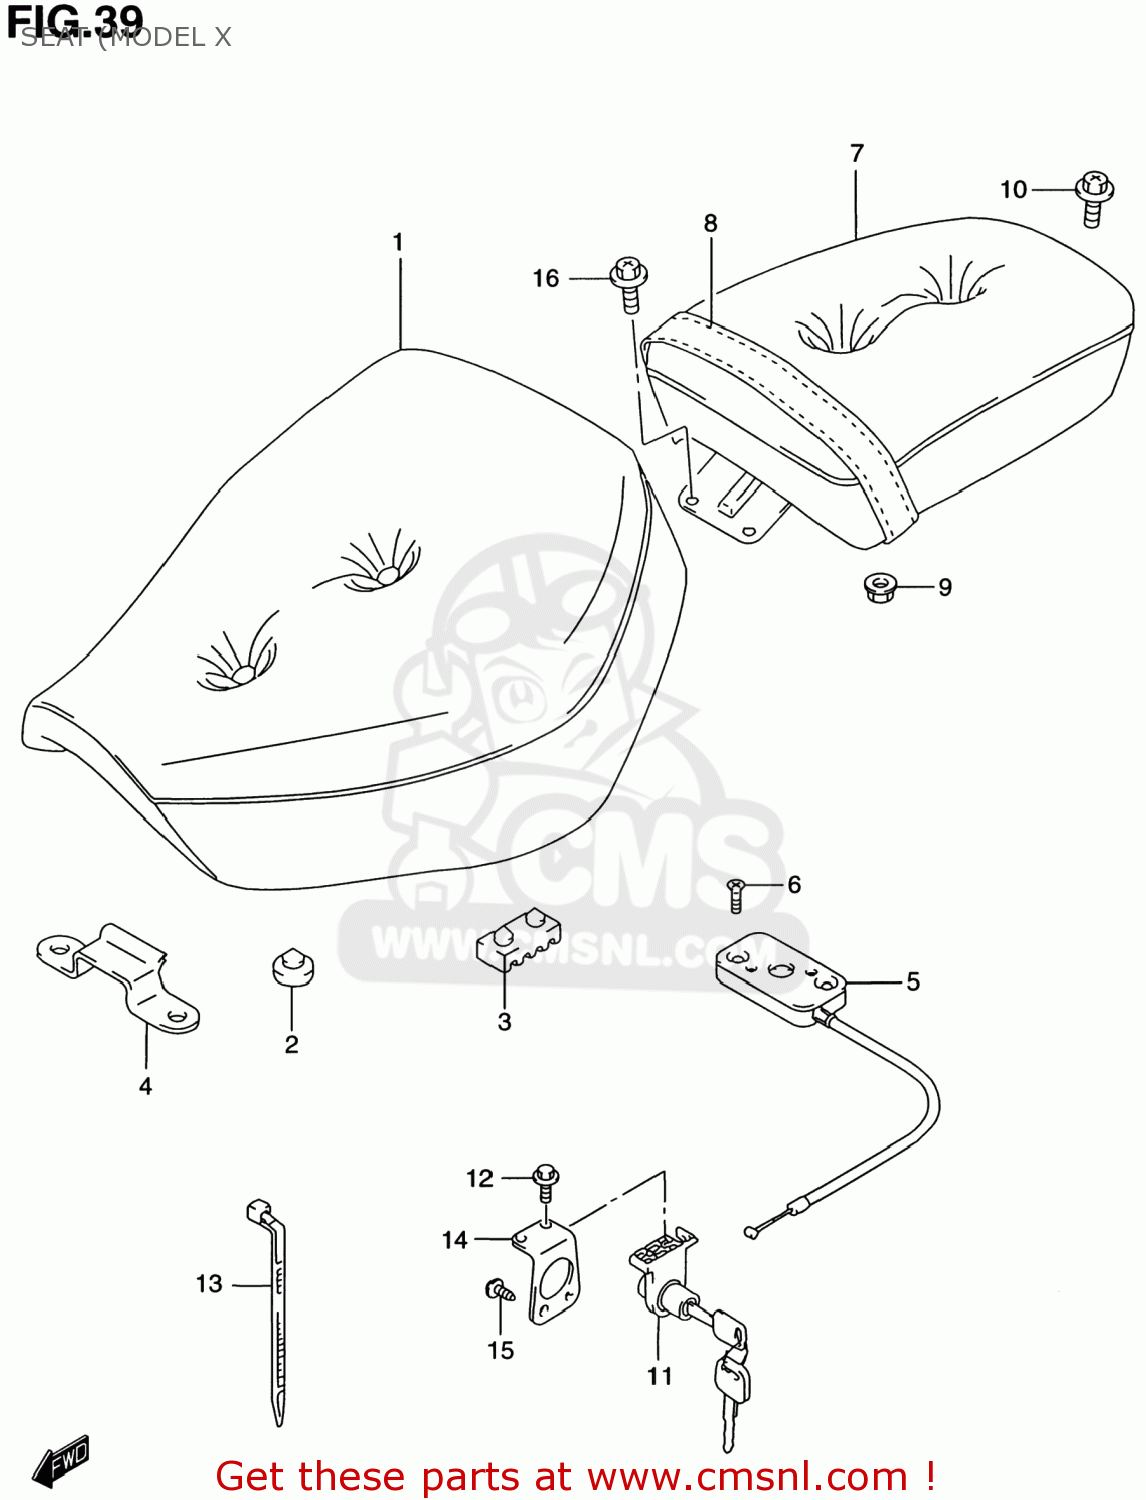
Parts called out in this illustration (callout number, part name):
1	SEAT ASSEMBLY
2	CUSHION,SEAT
3	CUSHION,SEAT(40X20X15)
4	PLATE,FR SEAT HOOK
5	BRACKET,SEAT SUPPORT
6	SCREW
7	SEAT ASSEMBLY,PILLION
8	BAND,SEAT(BLACK)
9	NUT
10	BOLT(8X16)
11	LOCK SET,SEAT
12	BOLT
13	CLAMP(L:220)
14	BRACKET,SEAT LOCK
15	SCREW
16	BOLT(6X12)
